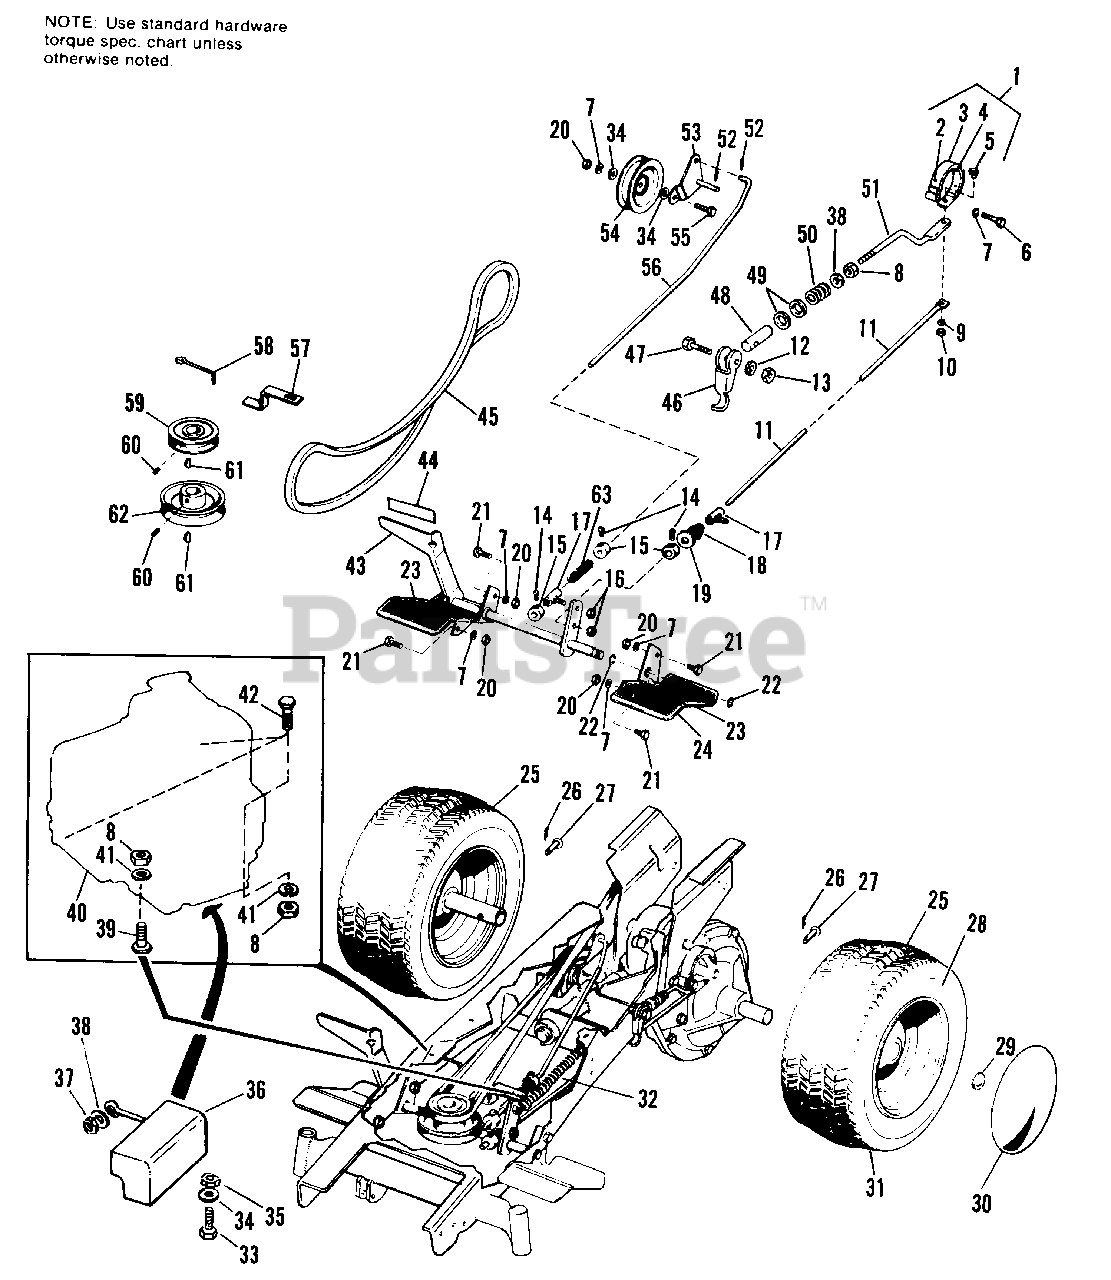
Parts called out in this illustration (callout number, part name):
1	BAND ASSY., Brake
2	RIVET, #7 x 1/4
3	BAND, Brake
4	LINING, Brake
5	CAPSCREW, Hex Hd., 1/4-20 x 3/4
6	CAPSCREW, Hex Hd., 3/8-16 x 1-1/2
7	LOCKWASHER, 3/8
8	NUT, Hex, Full, 5/16-18
9	LOCKWASHER, 1/4
10	NUT, Hex, Full, 1/4-20
11	ROD, Brake
12	LOCKWASHER, Double, 1/4
13	LOCKNUT, Hex, 1/4-20
14	SETSCREW, 1/4-20 x 3/8
15	COLLAR, Set
16	LOCKNUT, Hex, 5/16-18
17	GUIDE ASSY., Rod
19	WASHER, Plain, 3/8
20	NUT, Hex, Full, 3/8-16
21	CAPSCREW, Hex Hd., 3/8-16 x 3/4
22	RING, Snap
23	COVER, Footrest
24	FOOTREST, L.H.
25	WHEEL & TIRE ASSY., Rear
26	PIN, Cotter, 1/8 x 3/4
27	PIN
29	BUTTON, Plug
30	CAP, Hub, Rear
31	TIRE, Tubeless
32	SPRING, Return
33	SCREW, Hex, Taptite, 3/8-16 x 1-1/2 (990905 Only)
34	WASHER, Plain, 5/16 (Qty. 3 on 990778 & 990779 Only)
35	LOCKNUT, Hex, 3/8-16 (990905 Only)
36	GUARD ASSY. (990905 Only)
37	LOCKNUT, Hex, 5/16-18 (990905 Only)
38	WASHER, Plain, 1/4 (990905 Only)
39	CAPSCREW, Special
41	LOCKWASHER, 5/16
42	CAPSCREW, Hex Hd., 5/16-18 x 1-1/2
43	SHAFT ASSY., Clutch
44	PAD, Pedal
45	V-BELT, Drive
46	LEVER, Parking Brake
47	CAPSCREW, Hex Hd., 1/4-20 x 1-1/4
49	WASHER, Plain, 1/2
51	ROD, Parking Brake
52	PIN, Cotter, 1/8 x 3/4
53	BRACKET ASSY., Pulley
54	PULLEY, Idler
55	CAPSCREW, Hex Hd., 3/8-16 x 1-1/4
56	ROD, Clutch
57	STOP, Belt
58	STOP, Belt
59	PULLEY, Engine, Small
60	SETSCREW, 5/16-18 x 1/2
62	PULLEY, Engine, Large
63	SPRING, Compression
